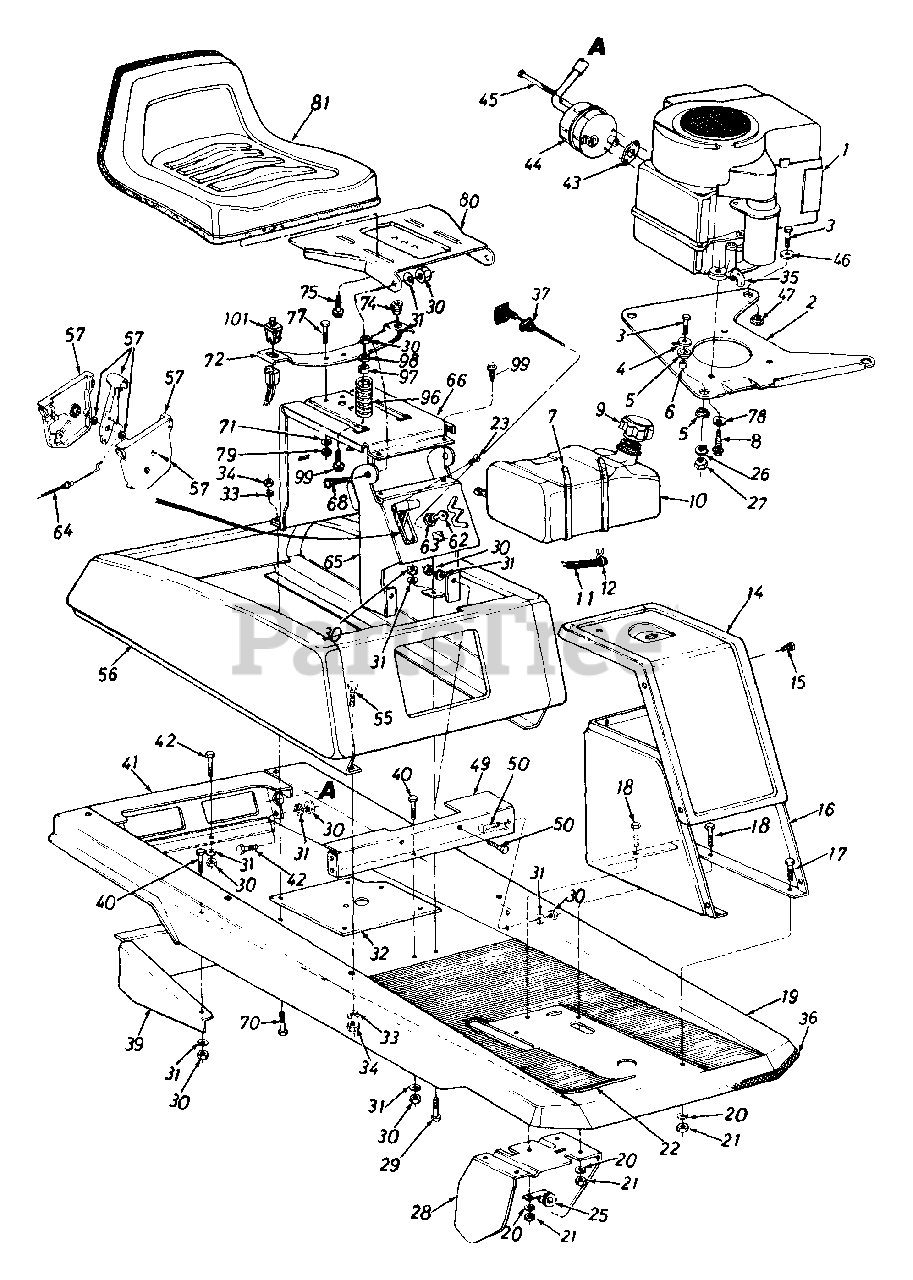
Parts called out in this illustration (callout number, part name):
1	Engine
4	Fl-Wash. .330" I.D. x 1.125" O.D.
5	Engine Mounting Grommet
6	Spacer .315" I.D. x .50" O.D. x .520" Lg.
7	Cable Tie 30.6 Lg.
8	Hex Wash. Hd. Self-Tap Scr. 3/8-16 x 1.25" Lg.
9	Gas Cap
10	Fuel Tank
11	Fuel Line - 26" Lg.
12	Hose Clamp - 1/2" O.D. Tube
22	Floor Mat
23	Truss Mach. AB-Tap Scr. #10 x .50" Lg.
25	Clamp
26	L-Wash. 5/16" I.D.
27	Hex Nut 5/16-24 Thd.
28	Clutch-Brake Pedal Ass'y.
29	Hex Bolt 5/16-18 x .75" Lg
30	Hex Nut 5/16-18 Thd.
31	L-Wash. 5/16" I.D.
34	Hex Nut 1/4-20 Thd.
35	90ø Elbow Male To Female
36	Trim Strip 18" Lg.
37	Choke Control
43	Exhaust Gasket (8 H.P.)
44	Muffler Ass'y (8 H.P.)
45	Shld Bolt (8 H.P.)
46	Fl-Wash .330" I D x 1.25" O.D.
47	Flange Wash. 320" I D x .750" O.D.
49	Seat Support & Frame Brkt
50	Hex Bolt 5/16-18 x 75" Lg
55	Hex Bolt 1/4-20 x 50" Lg
57	Throttle Control Box Ass'y.
62	Ignition Key
63	Ignition Switch
64	Throttle Control Wire 35" Lg.
70	Hex Tap Scr. 1/4-20 x 10" Lg.
71	L-Wash 5/16" I.D.
72	Seat Spring
74	Grommet
75	Hex Wash Hd Tap Scr. 3/8-16 x 3/4" Lg
77	Hex Bolt 5/16-18 x .75" Lg.
78	Bell-Wash. .345" I.D. x .88" O.D.
79	Hex Cent. L-Nut 5/16-18 Thd.
80	Seat Pivot Bracket
81	Seat Ass'y Comp
96	Compression Spring 2.7" Lg.
97	Bushing
98	Fl-Wash .344" I.D. x .875"
99	Hex Bolt 5/16-18 x 1" Lg. (Gr 5)
101	Seat Switch
